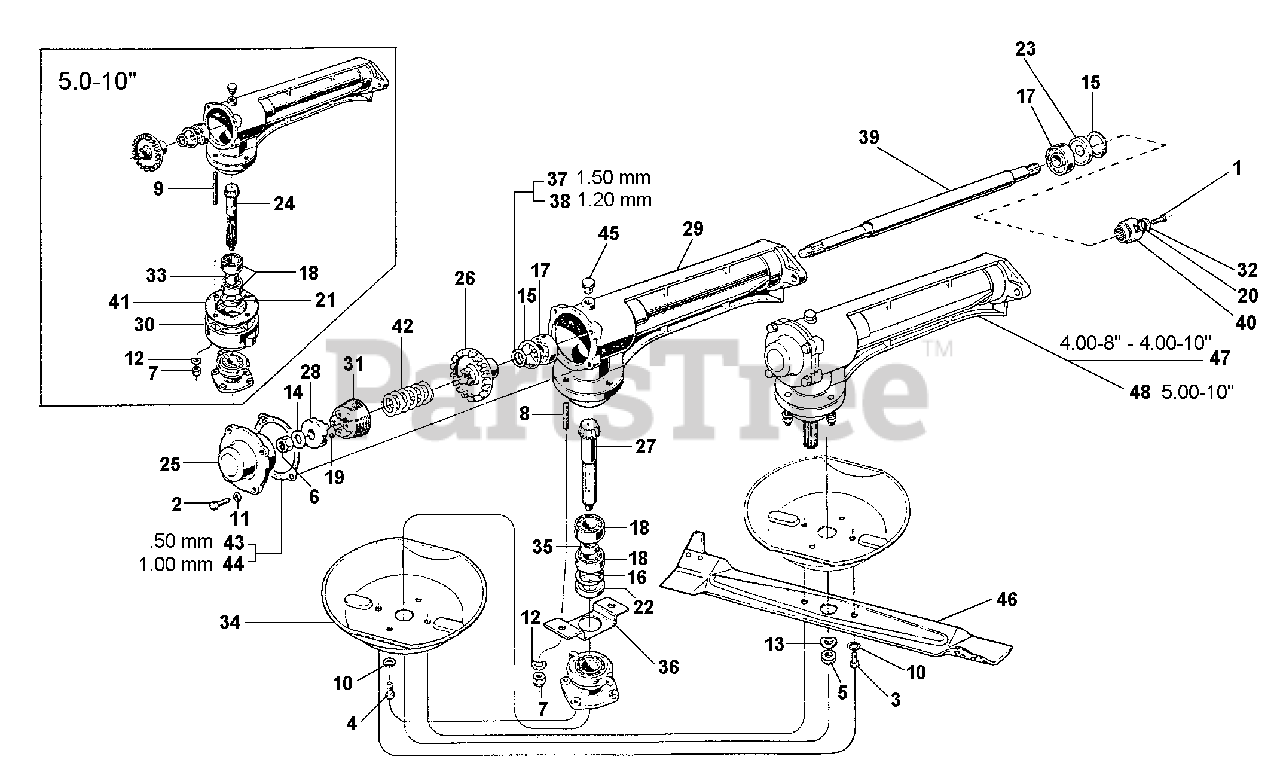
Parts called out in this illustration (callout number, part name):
1	SCREW TE M6X16
2	SCREW M6X20
3	SCREW M8X14
4	SCREW M8X12
5	NUT, LOW M12
6	NUT M14X1.5
7	NUT SELF LOCKING, M10 LOW
8	STUD M10X37X19X15 8G
9	STUD M10X68X34X15
10	SUPER WASHER 8 DIN 6796
11	WASHER, LOCK 6.4
12	WASHER, LOCK 10.5
13	WASHER, LOCK 13
14	WASHER, LOCK 15
15	CIRCLIP, INTERN. D 47
16	CIRCLIP, INTERN. D 52
17	BEARING 20X47X14 6204
18	BEARING SKF 25X52X15 6205
19	BALL 5/16 RIV RB 7.938
20	O-RING 3062 15.54X2.62
21	OIL SEAL 25X40X7
22	OIL SEAL 25X52X7
24	BEVEL PINION
26	CONICAL GEAR
28	BRAKE COUPLING
29	LAWN MOWER CASING
30	SPACER FLANGE
32	WASHER 7X25X4
33	LONG SPACER
34	PROTECTION DISC
39	PROPELLER SHAFT
40	PTO COUPLER
42	BRAKE SPRING
45	BREATHER CAP 1/4 GAS
46	LAWN MOWER BLADE
47	GEAR ASSEMBLY
48	GEAR ASSEMBLY
